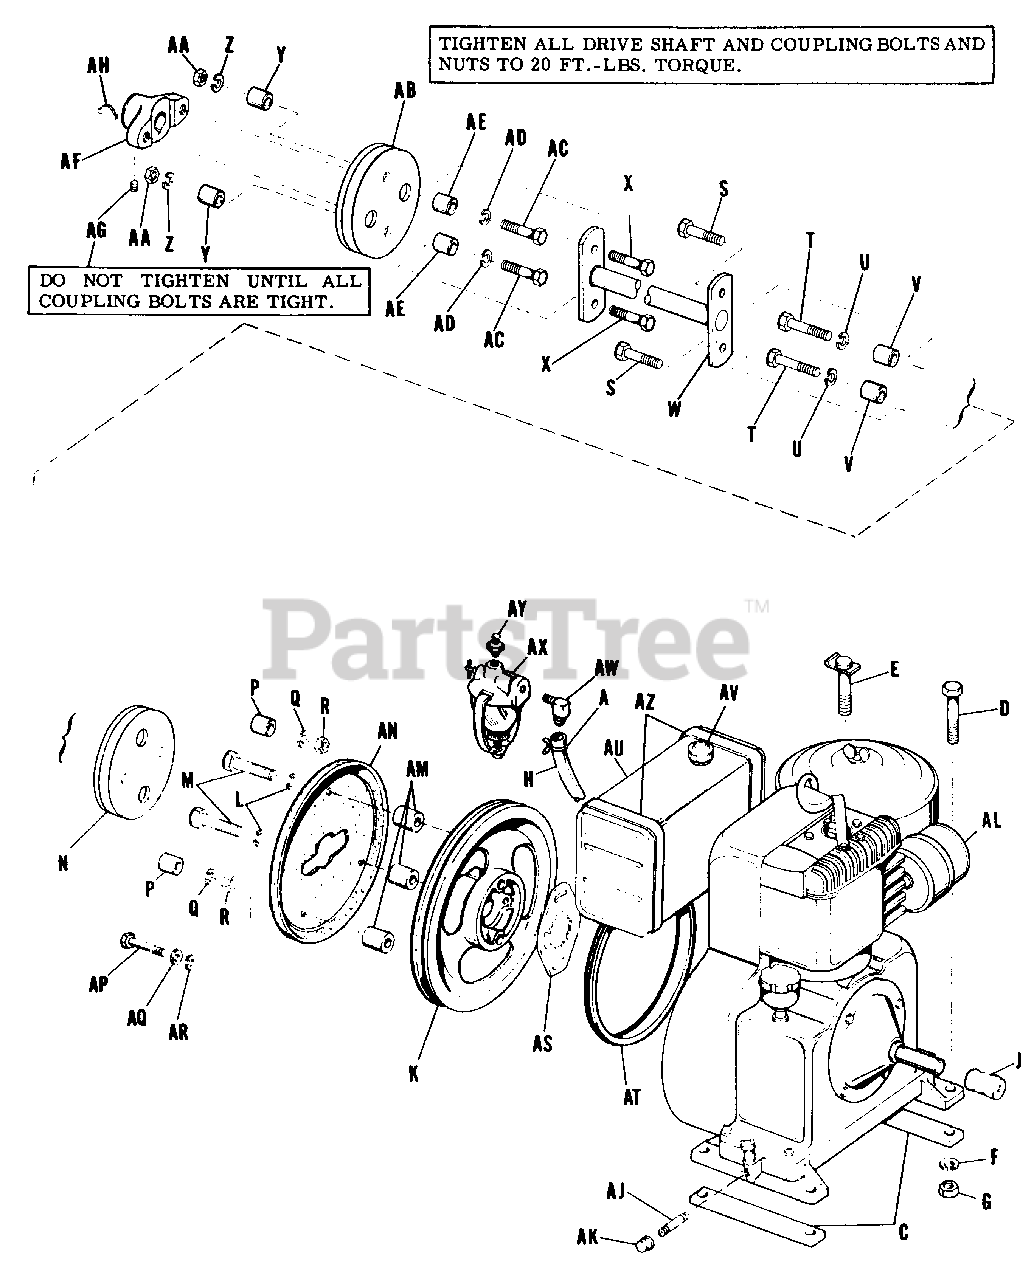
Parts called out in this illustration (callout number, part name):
A	Hose Clamp
C	Spacer, Engine
D	Screw, Cap, Hex., 3/8"-16 N.C. x 2" lg.
E	Screw Assembly, Engine, L.H. Rear
F	Washer, Lock, 3/8"
G	Nut, Hex., Full, 3/8"-16 N.C.
H	Hose, Fuel (flexible)
J	Guard Crankshaft Extension
K	Pully, Engine
L	Washer, Lock, 5/16"
M	Screw, Cap, Hex., 5/16"-18 N.C. x 1-3/4" lg.
N	Coupling Assembly
Q	Washer, Lock, 3/8"
R	Nut, Hex., Full, 3/8"-16 N.C.
S	Screw, Cap, Hex., 3/8"-16 N.C. x 1-1/2" lg.
T	Screw, Cap, Hex., 3/8"-16 N.C. x 1-3/4" lg.
U	Washer, Lock, 3/8"
W	Shaft Assembly, Drive
X	Screw, Cap, Hex., 3/8"-16 N.C. x 1-1/2" lg.
Z	Washer, Lock, 3/8"
AA	Nut, Hex., Full, 3/8"-16 N.C.
AB	Coupling Assembly
AC	Screw, Cap, Hex., 3/8"-16 N.C. x 1-1/2" lg.
AD	Washer, Lock, 3/8"
AF	Flange, Drive Shaft
AG	Screw, Set, Cup Point, Socket Head, 5/16"-18 N.C. x 5/16" lg.
AH	Key, Hi-Pro
AJ	Nipple, Pipe, 3/8" Std. x 2" lg.
AK	Cap, Pipe, 3/8" Std.
AL	Muffler, Exhaust
AN	Screen, Engine
AP	Screw, Cap, Hex. 1/4"-20 N.C. x 1-1/4" lg.
AQ	Washer, Plain
AR	Washer, Lock
AS	Nut, Lock
AT	Seal, Blower, Housing
AW	Fitting, Fuel Line.
AX	Filter Bowel Ass'y.
AY	Connector
AZ	Strap, Tank.
